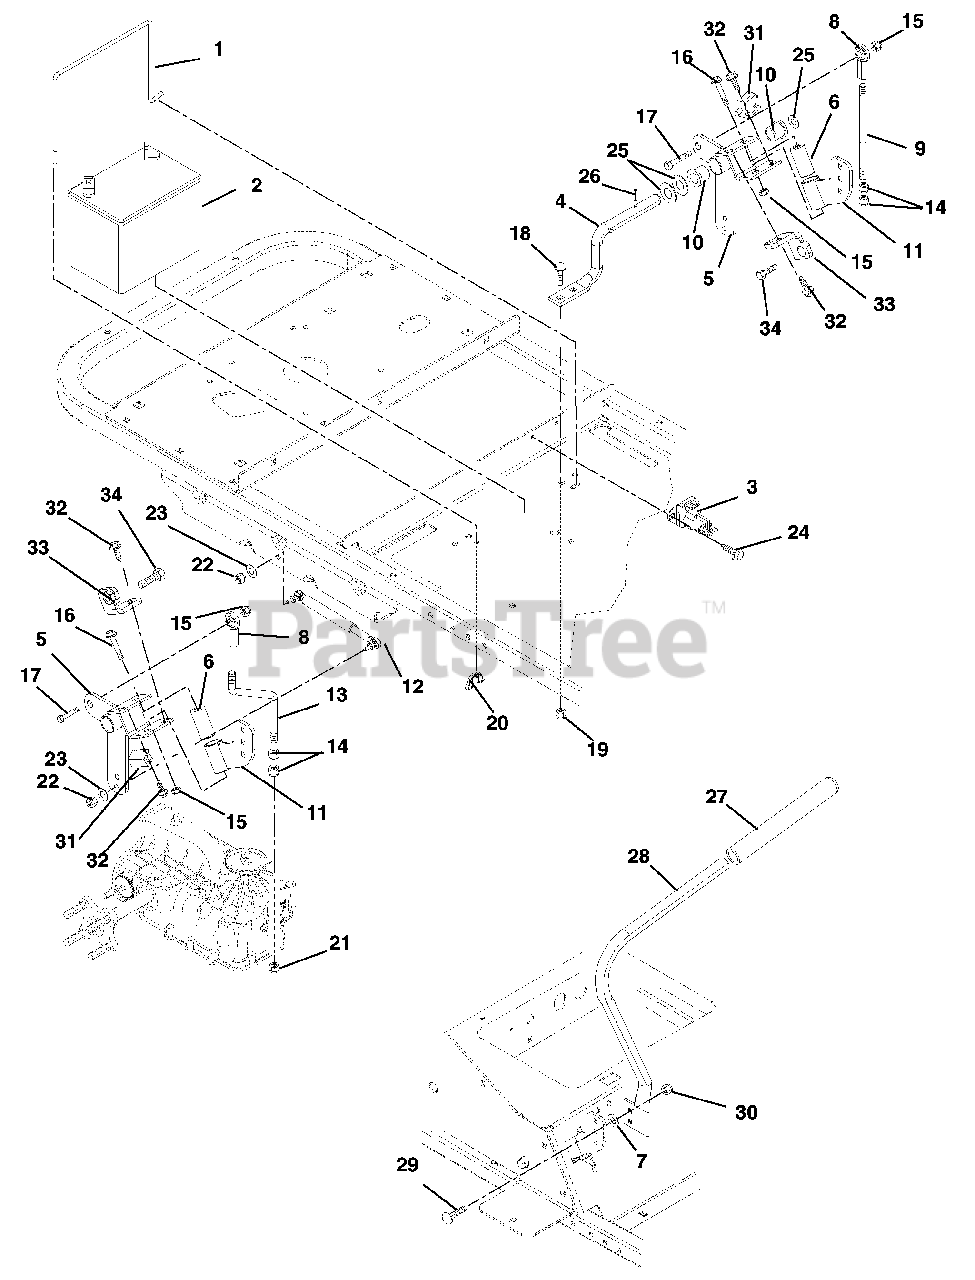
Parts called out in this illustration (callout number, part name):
1	Battery Rod
2	Battery (12 Volt, 330 CCA, 50 Min. Reserve Cap.)
3	Solenoid
4	Rod Pivot
5	Weldment, Control
7	Washer, Locking Extenal .326 x .599 x .031
8	Rod End, .50 Right Hand
9	Rod, Transaxle Left Hand
10	Bushing 1.00 x .75 x 1.00
11	Weldment, Handlebar
13	Rod, Transaxle Right Hand
14	Nut, Jam .50-20 Grade 2
15	Nut, Locking Top Flange .50-13
16	Bolt, Hex .50-13 x 3.00 Grade 5
17	Bolt, Hex .50-13 x 1.50 Grade 5
18	Bolt, Round Head Square Neck .38-16 x 1.00 Grade 5
19	Nut .38-16 Flange Nyloc
20	Nut, Locking Wing .25-20
21	Nut, Jam Nyloc .50-20 Grade 2
22	Nut, Hex M8-1.25
23	Washer, Locking .31 x .078 Regular
24	Screw, Tapping .25-20 x .37 Hex Washer Head
25	Washer, Flat Steel .754 x 1.00 x .032
26	Pin, Roll .188 x 1.13
27	Grip, Handlebar
28	Handlebar, Right Hand
28	Handlebar, Left Hand
29	Bolt, Round Head Square Neck .31-18 x .88 Grade 5
30	Nut 5/16-18 Flange Nyloc
31	Switch, Double Pole N.O./N.O.
32	Screw, Tapping 10-24 x .50 Hex Washer Head
33	Weldment, Handle Stop
34	Screw-Socket Head .25-20X1.25
